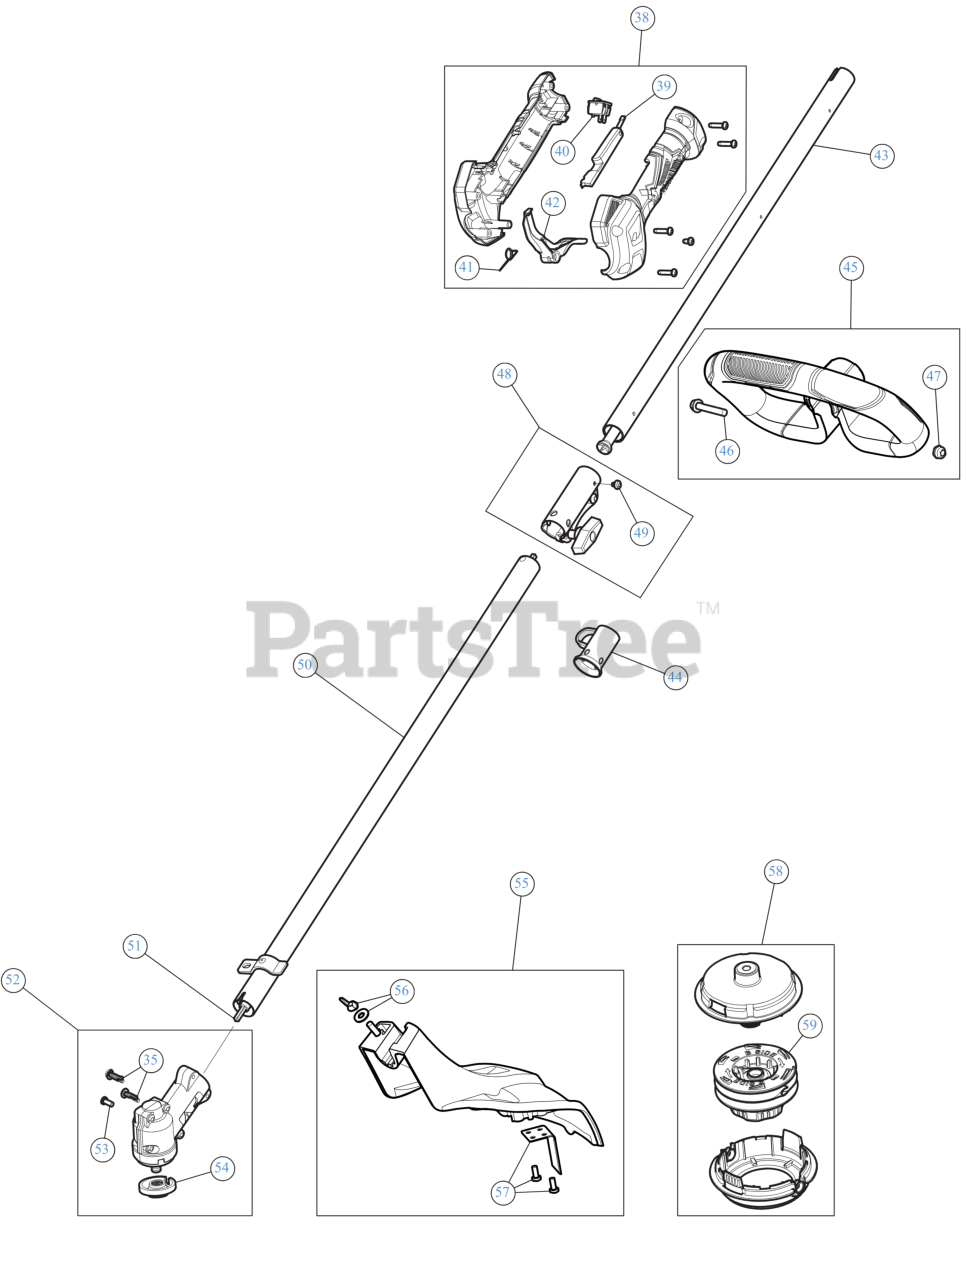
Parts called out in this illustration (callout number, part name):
38	THROTTLE GRIP ASSEMBLY
39	THROTTLE LOCK LEVER
40	SW, MOMENTARY ON/O
41	TRIGGER SPRING
42	THROTTLE TRIGGER
43	BOOM ASSEMBLY UPR
44	HANGER
45	D HANDLE
46	BOLT 1/4-20X1 1/2
47	NUT 1/4-20 NYLOC
48	COUPLER ASSEMBLY
49	SCREW, 10-32X.250 TA
50	LOWER BOOM ASSEMBLY
51	LOWER DRIVE SHAFT
52	GEARBOX LCBC
53	SCREW, 8-32 x .312 P
54	CUTTING HEAD SPACER
55	GUARD
56	BLADE GUARD MOUNTING HARDWARE
57	BLADE ASSEMBLY W/HDW
58	CUTTING HEAD
59	BUMP KNOB
